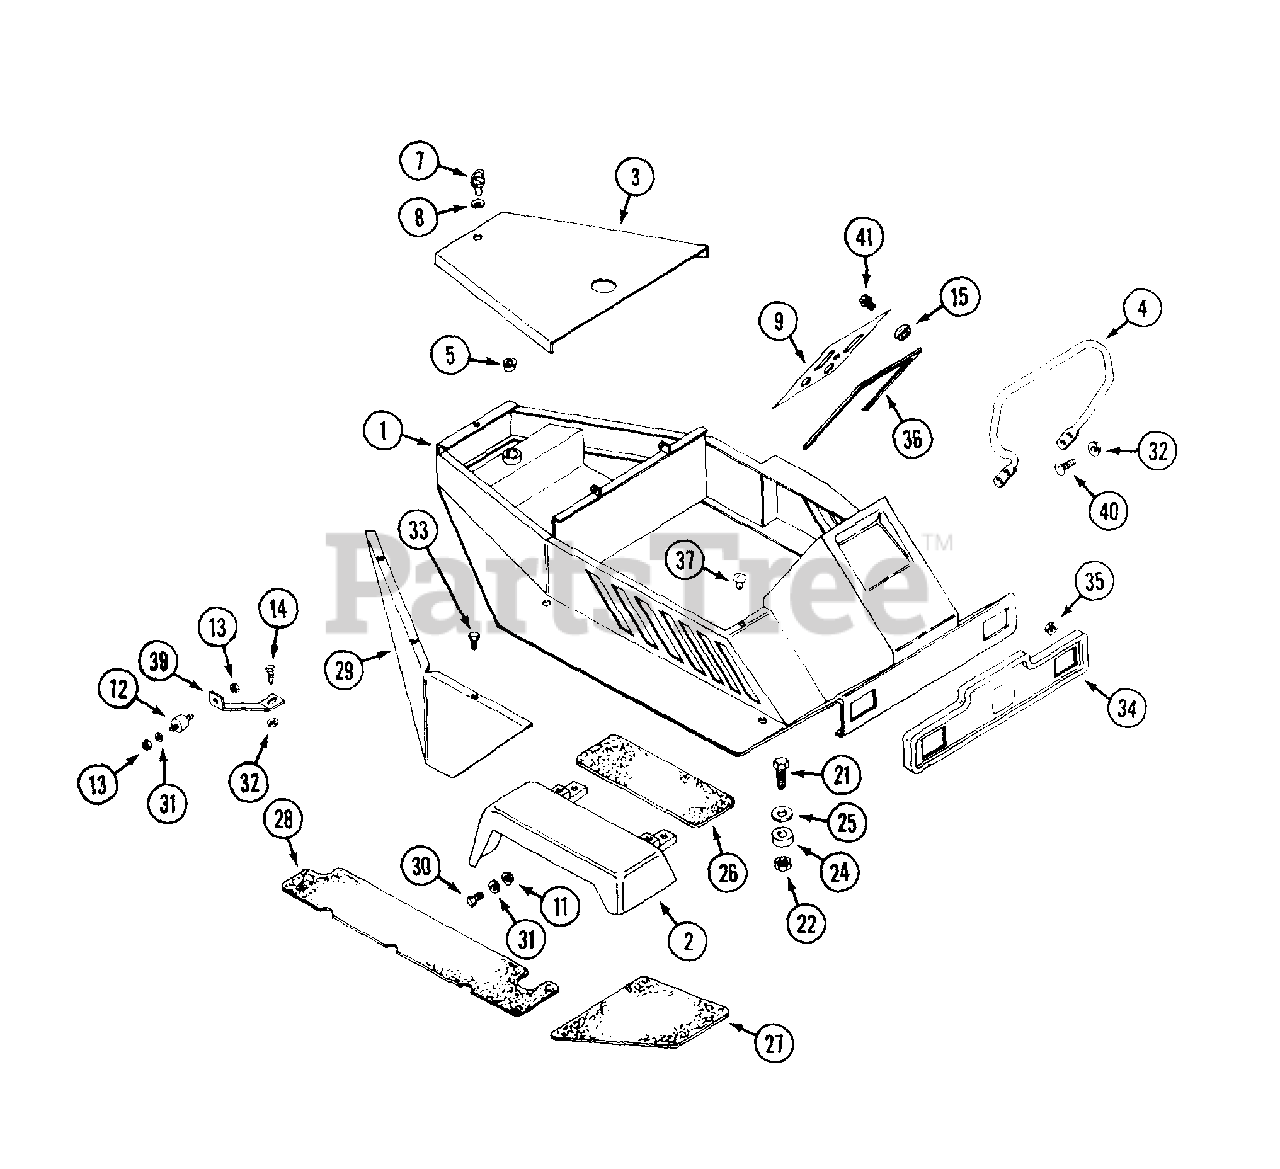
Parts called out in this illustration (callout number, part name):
1	BODY
2	FENDER - R.H.
4	BAR - handle
5	BEARING - rear wheel fork
7	STUD - fastener
8	GROMMET - fastener
11	NUT - flange lock
12	MOUNT - rubber
13	NUT - 1/4" - 20 lock
14	BOLT - 5/16" - 18 x 3/4"
15	NUT - #10 - 24 flange lock
21	BOLT - 1/2" - 13 x 3"
22	NUT - 1/2" lock
24	MOUNT - body, rubber
25	WASHER - mount, body
27	PAD - footrest, front L.H.
28	PAD - footrest, rear L.H.
30	BOLT - 1/4" - 20 x 3/4"
31	WASHER - 1/4"
32	NUT - 5/16" - 18 flange lock
33	BOLT - 5/16" - 18 x 5/8" black
35	NUT - #8 - 32 flange lock
36	TRIM - 27" (cut to length)
37	BUMPER - nylon
39	BRACKET - fender support
40	BOLT - 5/16" - 18 x 1" carriage
41	SCREW - #12 x 1/2"
